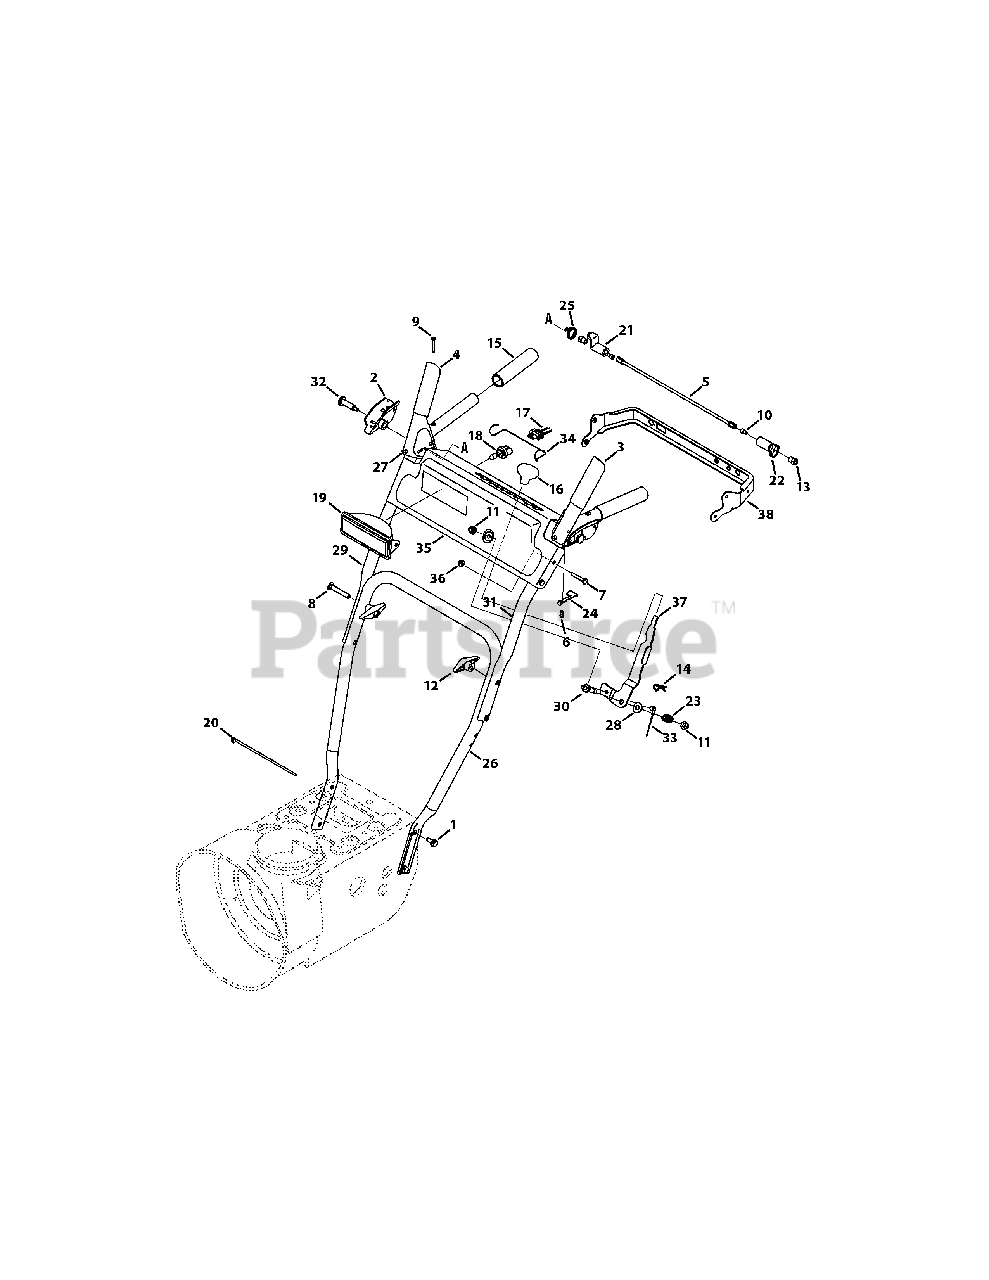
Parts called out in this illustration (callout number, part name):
1	Taptite Screw, 5/16-18 x .750
2	Clutch Lock Handle Assembly, LH
2	Clutch Lock Handle Assembly, RH
3	Engagement Assembly, LH
4	Engagement Assembly, RH
5	Clutch Pivot Lock Rod Assembly
6	Hex Washer Screw, #8-16 x .50
7	Hex Washer Screw, 1/4-20 x .625
7	Hex Head Screw, 1/4-20 x 1.50
8	Carriage Screw, 5/16-18 x 2.25
9	Machine Screw, #10-24 x 1.375
10	Socket Screw, 1/4-20 x .50
11	Flange Lock Nut, 5/16-18
12	Wing Knob
13	Hex Nut, 1/4-20
14	Click Pin, .092 x 1.64
15	Grip, 1.0 ID x 5.0 LG
16	Shift Knob
17	Snow Thrower Harness
18	Halogen Lamp
19	Lens/Lamp Assembly Housing
20	Cable Tie
21	Lock Plate
22	Clutch Lock Cam
23	Compression Spring, .39 x .60 x .88
24	Clutch Lock Spring
25	Torsion Spring, .8156 ID x .3038
26	Lower Handle
27	Rubber Bumper, .62 OD x .22 Thick
28	Flat Washer, .385 x .870 x .092
29	Upper RH Handle
30	Shoulder Bolt, 5/16-18 x .905
31	Upper LH Handle
32	Shoulder Screw, .437 x 1.345 x 1/4-20
33	Speed Selector Cable
34	Headlight Retainer
35	Handle Panel w/ Light - Red
35	Handle Panel w/ Light - Black
35	Handle Panel w/o Light - Red
35	Handle Panel w/o Light - Black
36	Flange Lock Nut, 1/4-20
37	Speed Shift Lever
38	Panel Bracket
38	Amp Connector
